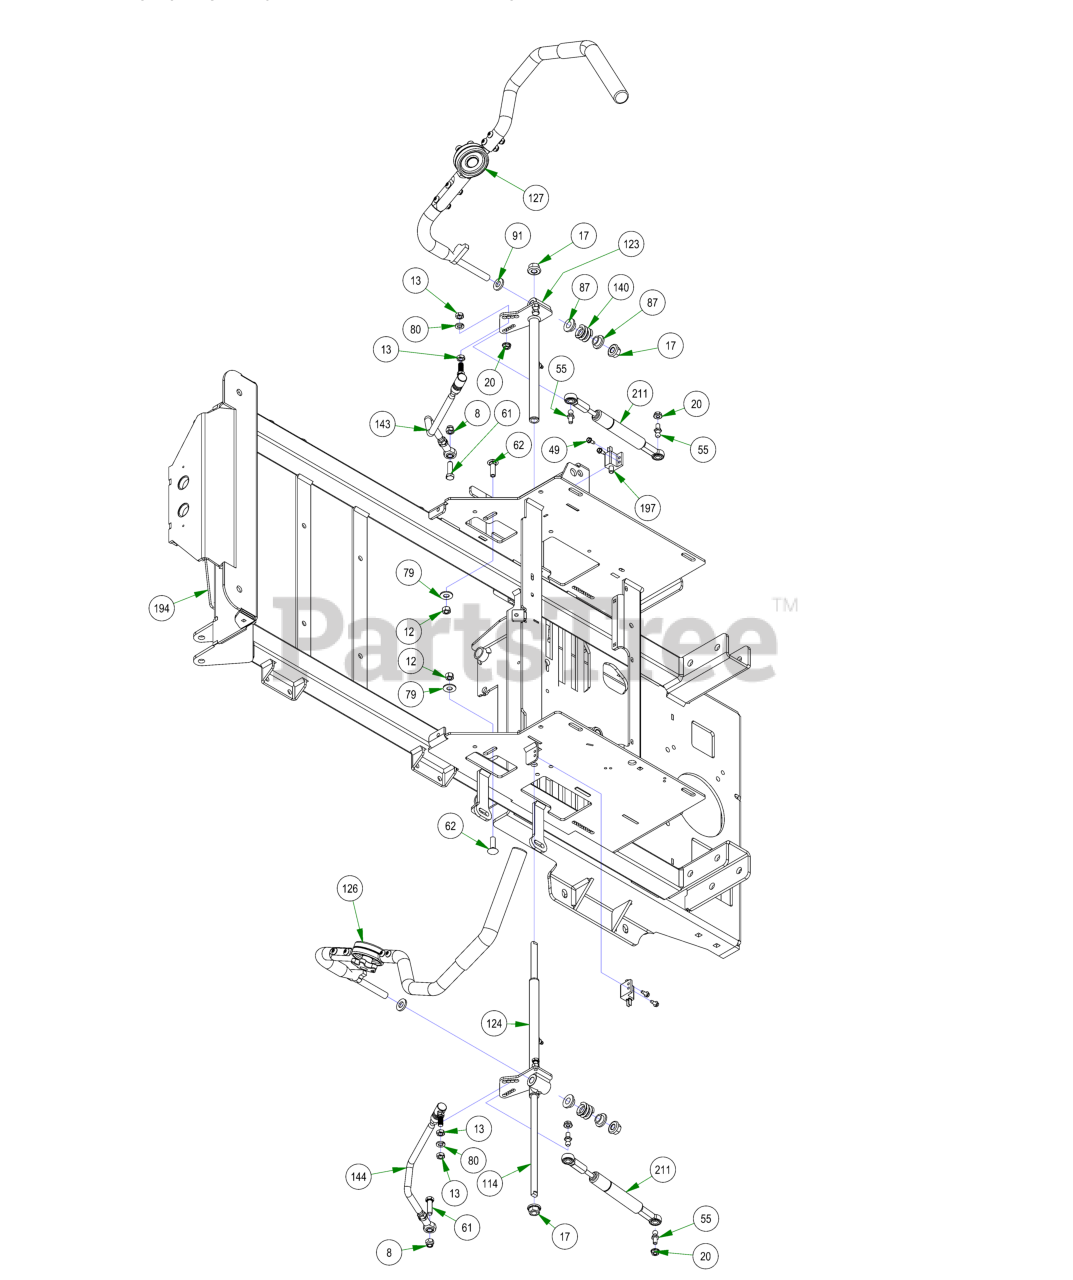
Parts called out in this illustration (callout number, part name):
8	3/8-16 NYLON INSERT LOCKNUT ZINC
12	3/8-16 HEX NUT ZINC
13	3/8-24 HEX NUT ZINC YELLOW
17	1/2-13 NYLON INSERT FLANGE LOCKNUT ZINC
20	5/16-18 HEX SERRATED FLANGE NUT HARD/ZINC
49	12-24 X 1/2 HEX WASHER UNLSOT F TCS ZINC
55	10mm Damper Ball Stud-Steering
61	3/8-16 X 1-1/4 HEX CAP SCREW (GR.5) ZINC
62	3/8-16 X 1-1/4 CARRIAGE BOLT ZINC
79	3/8 FLAT WASHER USS (1" OD) ZINC
80	3/8 SPLIT LOCKWASHER ZINC
87	.525 ID SHOULDER WASHER NYLON
91	.505 ID X 1.000 OD X .125 THICK FLAT WASHER NYLON
114	2021 Maverick Steering Actuator Rod
123	2021 Maverick Drive Arm Actuator RH Assembly
124	2021 Maverick Drive Arm Actuator LH Assembly
126	2018 Adjustable Steering Arm - Left
127	2018 Adjustable Steering Arm - Right
140	Drive Lever Spring
143	Push Rod-Right
144	Push Rod-Left
194	2023 Maverick Frame - Painted
197	Safety Switch
211	Steering Damper
